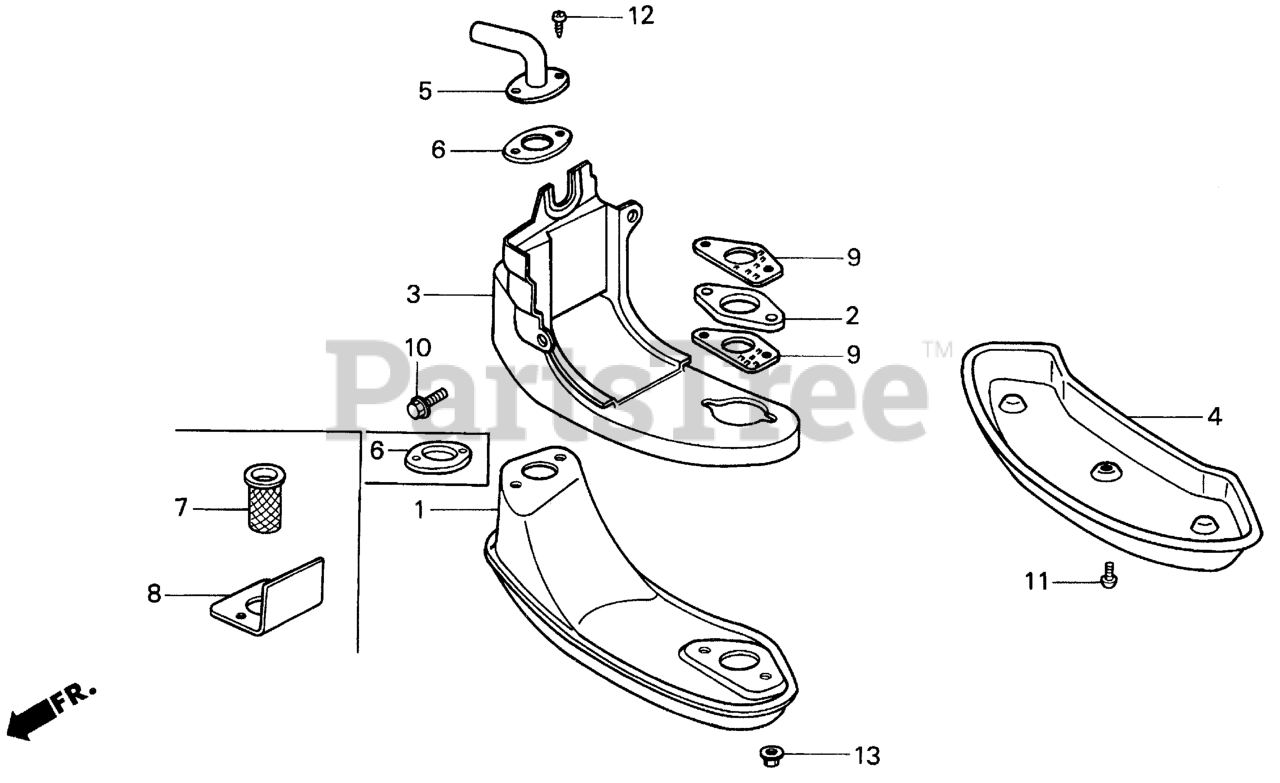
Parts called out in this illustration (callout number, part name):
1	MUFFLER
2	FLANGE, MUFFLER
3	PROTECTOR, MUFFLER
4	PROTECTOR, MUFFLER (LOWER)
5	PIPE, TAIL
6	GASKET, TAIL PIPE
6	GASKET, TAIL PIPE (NOT AVAILABLE)
7	ARRESTER, SPARK
8	PLATE, ARRESTER NUMBER
9	GASKET, MUFFLER Use from Engine SN 2506046.
10	BOLT, FLANGE (6X12) (CT200)
11	SCREW, TAPPING (4X8) Use from Engine SN 1081364.
11	SCREW, PAN (5X6)
12	SCREW, TAPPING (4X10)
13	NUT, FLANGE (6MM)
